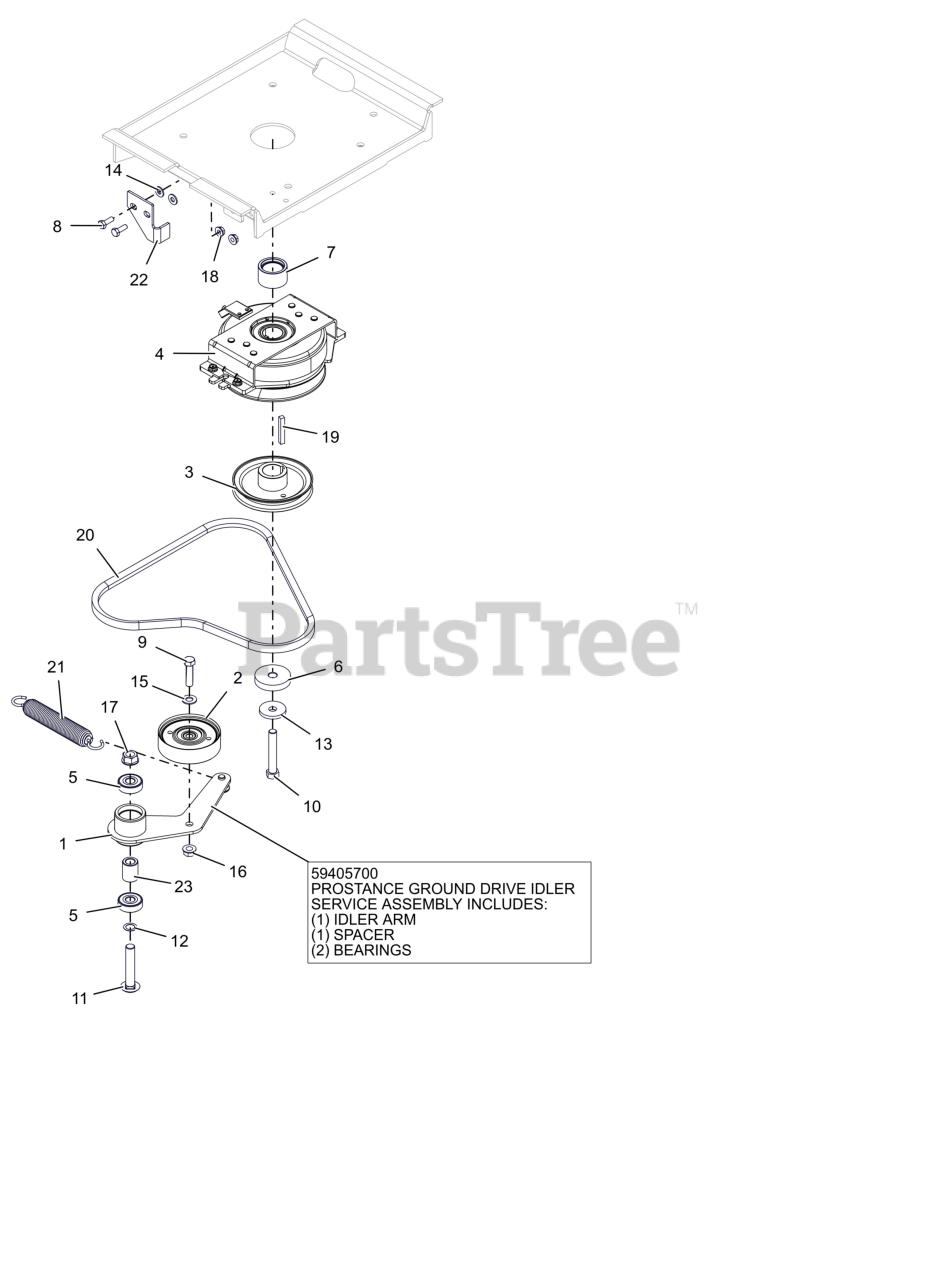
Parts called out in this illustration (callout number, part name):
1	WLDMT, IDLER ARM
1	PROSTANCE GROUND DRIVE IDLER ASSEMBLY
2	IDLER- FLAT 3.5" NO FLANGES
3	SHEAVE, ENGINE 4.50 OD x 1.127 ID (BLACK)
4	CLUTCH, OGURA GT2.75-BB05
5	BRG-BALL .500X1.38X.437
6	SPACER, .450X2.00X.396
7	SPCR, CLUTCH
8	BLT, HEX .25-20X.75 G5 ZCC
9	BLT, HEX .38-16X1.50 G5 ZCC
10	BLT, HEX .44-20X2.75 G8 ZCC NT
11	BLT,RHSSN .500-13 X 2.75 G5 ZCC
12	WASHER, .500X.750X.020 THRUST
13	WASHER, 7/16" SPRING DISK
14	WSHR,FLT .281X.625X.065 ZCC
15	WSHR,FLT .406X.812X.065 ZCC
16	NUT-LK-CTR-FLG .375-16 GF ZCC
17	NUT-LK-CTR-FLG .500-13 GG ZCC
18	NUT-LK-TOP-FLG .250-20 GF ZCC
19	KEY-STR .25X1.75X.25
20	V-BELT, A -RAW EDGED LAMINATED
21	SPRING, EXTENSION 1.0 X 6.65
22	BRKT, CLUTCH STOP (BLACK)
23	SPACER .510 X .867 X 1.1485
